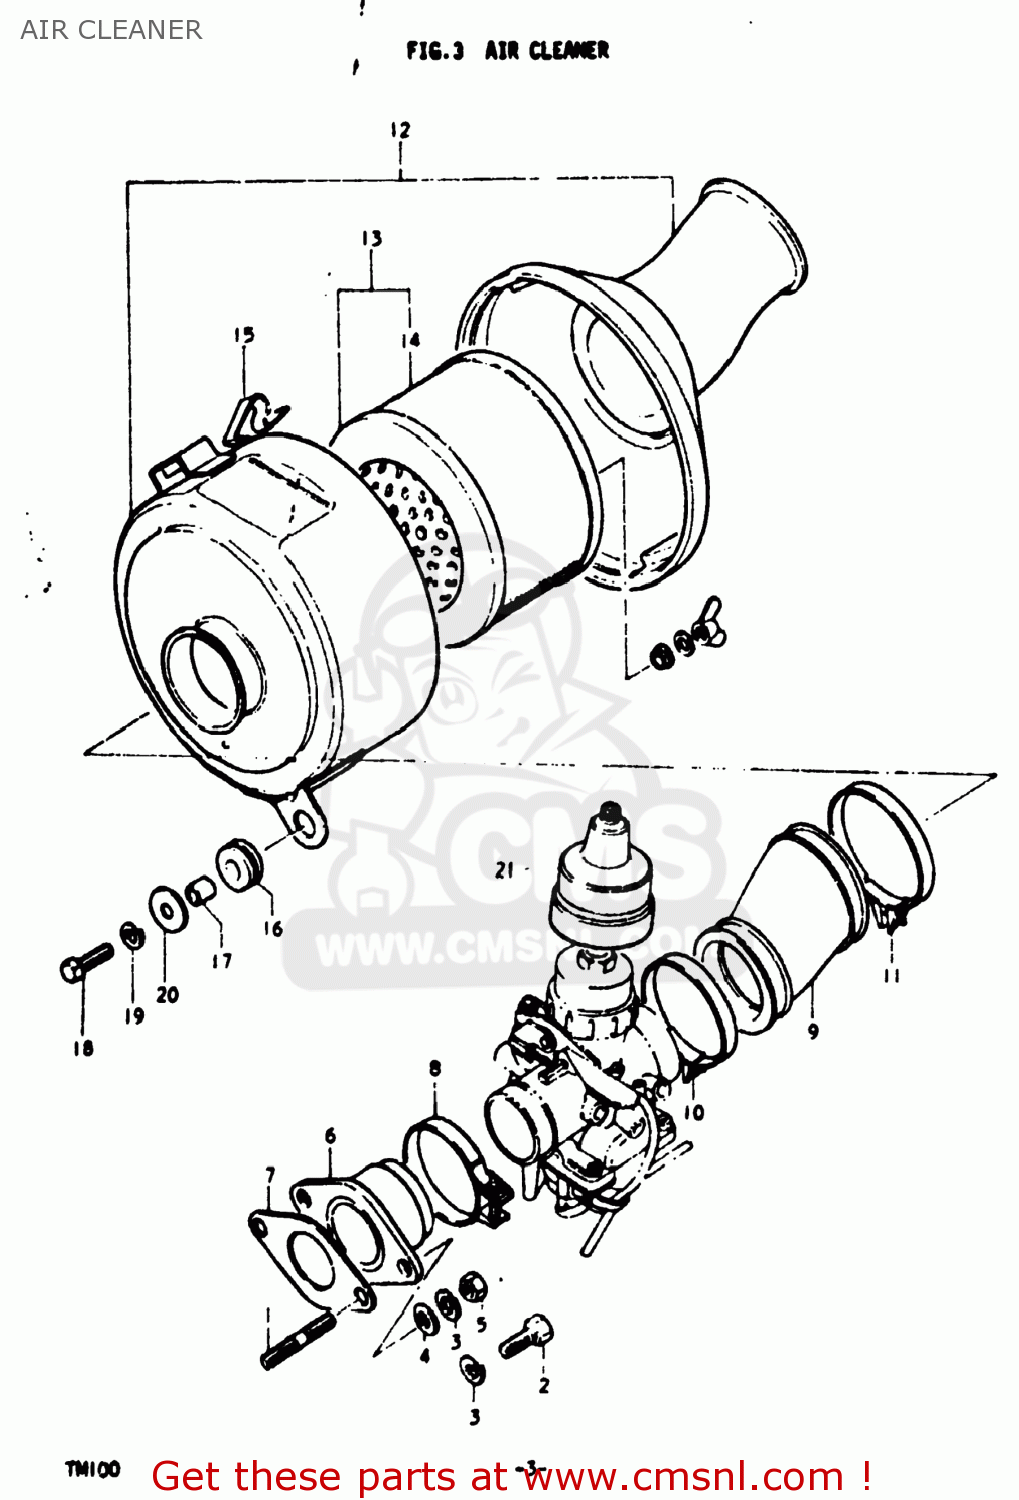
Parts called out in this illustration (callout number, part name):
1	STUD BOLT
2	BOLT
3	LOCK WASHER
4	WASHER
5	NUT
6	PIPE,INTAKE
7	GASKET,CARBURETOR (MCA)
8	CLAMP
9	HOSE,CARBURETOR AIR INLET
10	CLAMP
11	CLAMP
12	CLEANER ASSEMBLY,AIR
13	FILTER,AIR CLEANER
14	ELEMENT,AIR CLEANER
15	SPRING,AIR CLEANER
16	CUSHION
17	SPACER (7X9X7)
18	BOLT
19	LOCK WASHER
20	WASHER (6.5X20X1.2)
21	CAP
